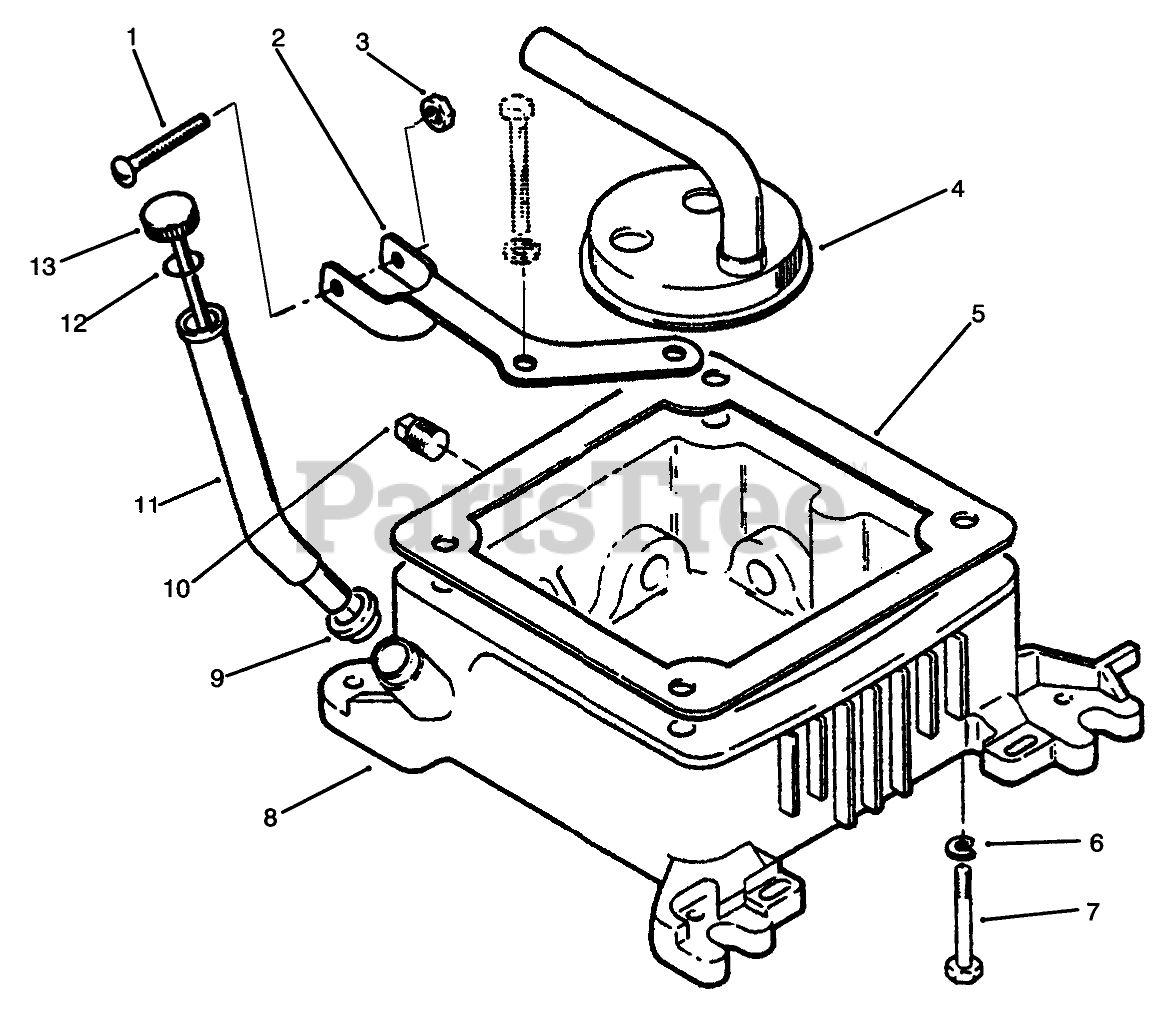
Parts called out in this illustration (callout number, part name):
1	SCREW - PAN HEAD
2	BRACKET-FILL TUBE
3	NUT - SPEED
4	OIL CUP ASM
5	GASKET
6	WASHER-FLAT
7	HHCS 3/8-16 X 3 3/4
8	Base-Oil (Incl. Ref. #10)
9	SEAL-OIL FILL TUBE
10	PLUG - SQUARE HEAD
11	Tube-Oil Fill
12	SEAL 0-RING
13	Cap & Indicator-Oil Fill (Incl. Ref. #12)
